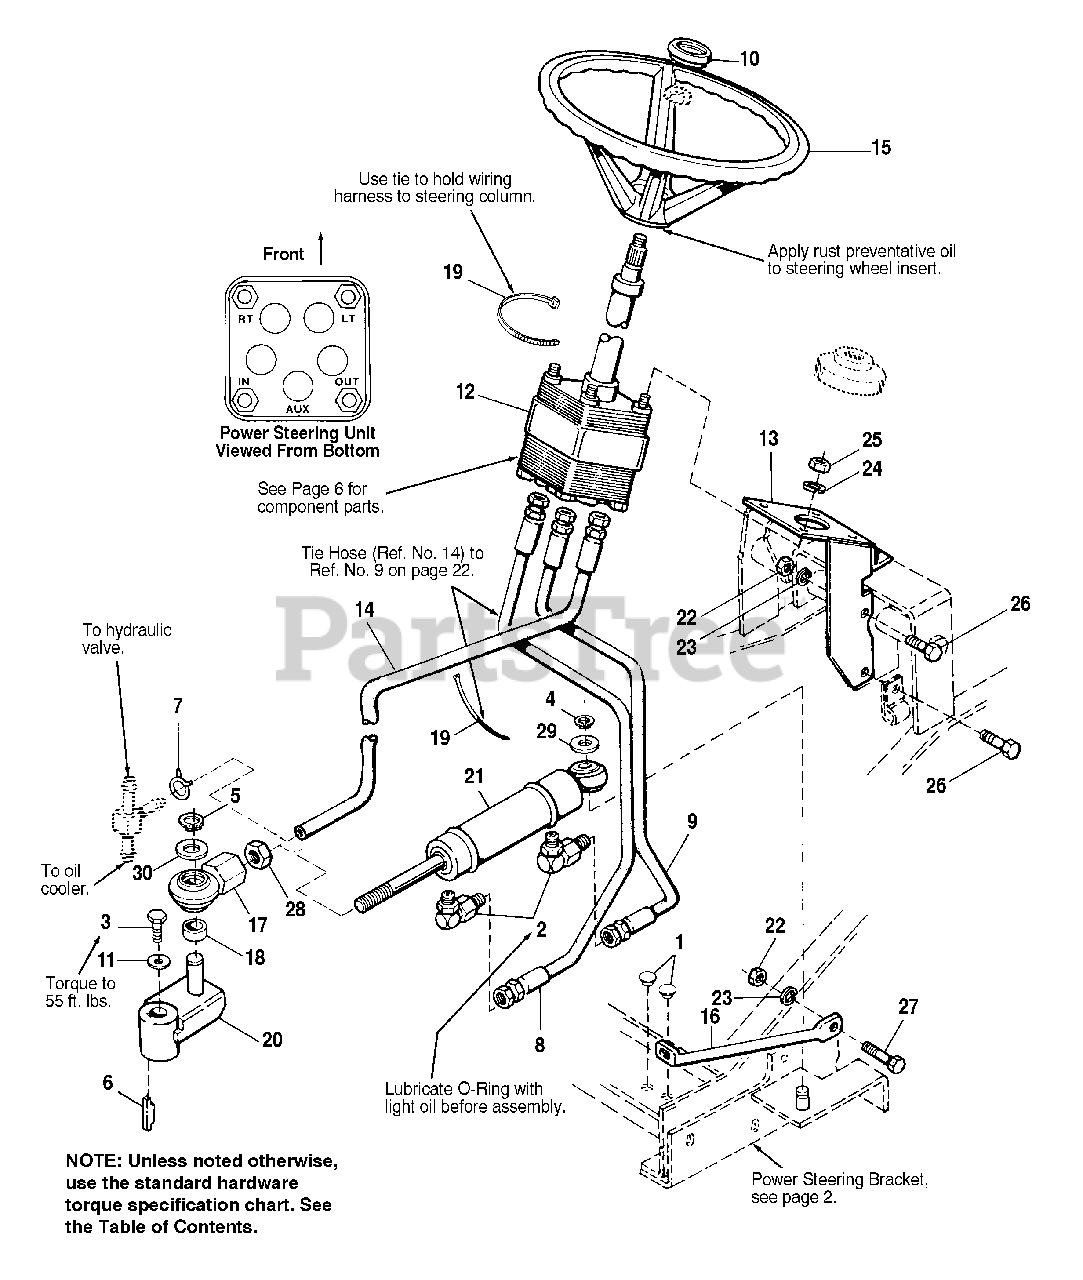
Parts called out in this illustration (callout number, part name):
1	PLUG, Plastic
2	FITTING, Hyd., 9/16-18 x 9/16-18 - 90 degree
3	CAPSCREW, Hex Hd., 3/8-16 x 7/8, Gr. 8
4	RING, Retaining, 5/8
5	RING, Retaining, 3/4
6	KEY, Hi-Pro, 1/4 x 3/4
7	HOSE CLAMP
8	HOSE ASSY., Hyd. (Valve to Cylinder)
9	HOSE ASSY., Hyd. (Valve to Cylinder)
10	CAP, Steering Wheel
11	WASHER, Spring
12	STEERING UNIT, Hydrostatic
13	SUPPORT ASSY., Steering Valve
14	HOSE ASSY., Hyd., (Valve to Cooler)
15	WHEEL ASSY., Steering
16	BRACE, Cylinder
17	BALL JOINT ASSY.
18	SPACER
20	ARM ASSY., Steering
21	CYLINDER, Power Steering
22	NUT, Hex, 3/8-16
23	LOCKWASHER, 3/8
24	LOCKWASHER, 5/16
25	NUT, Hex, 5/16-24
26	CAPSCREW, Hex Hd., 3/8-16 x 1, Gr. 5
27	CAPSCREW, Hex Hd., 3/8-16 x 1 -1/2, Gr. 5
28	NUT, Hex, 3/4-16
